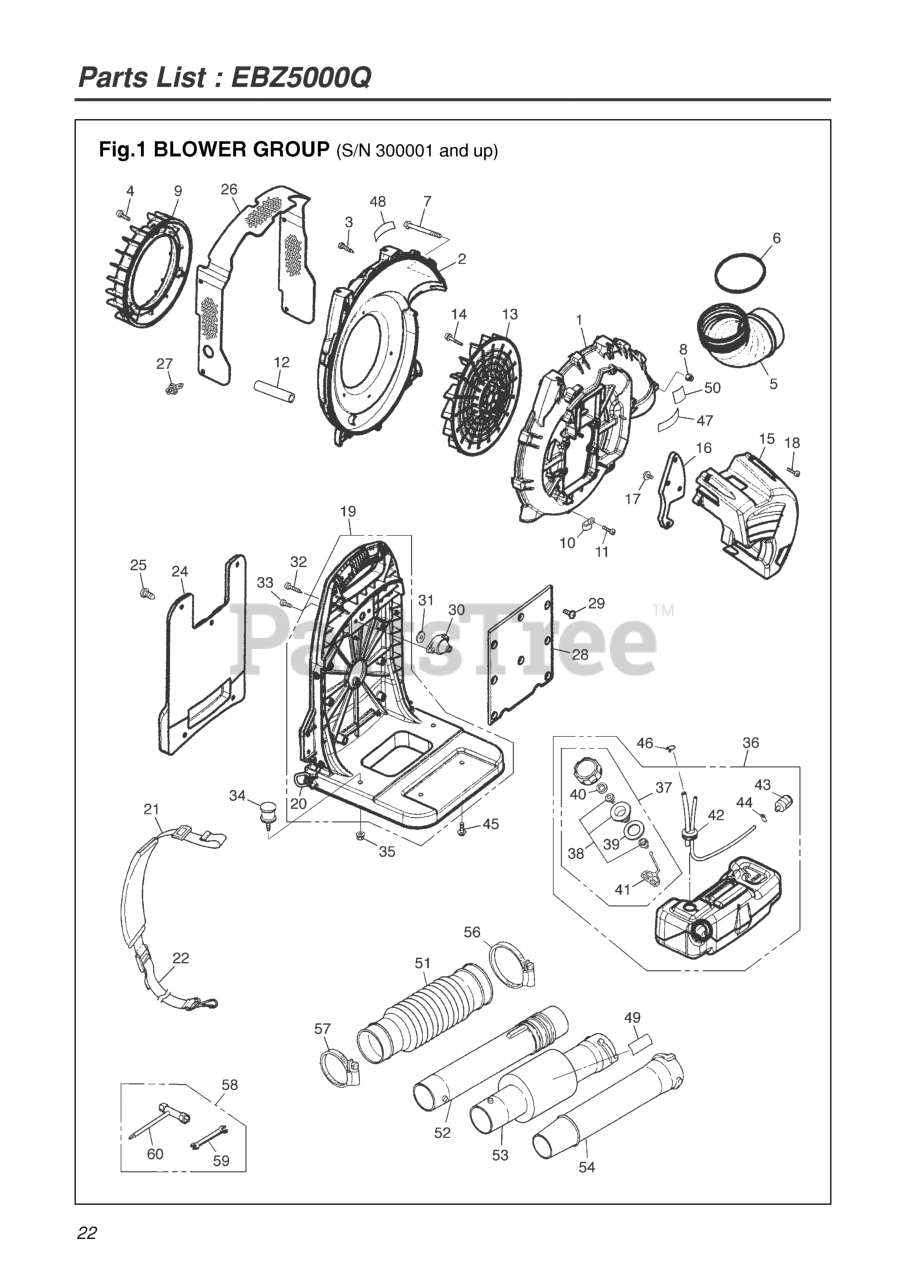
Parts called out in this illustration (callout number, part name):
1	CASE, VOLUTE
2	VOLUTE COVER(RPLS.T4017-31210)
3	SCREW
4	SCREW
5	ELBOW
6	O-RING
7	SCREW TORX
8	NUT (B)
10	CLAMP (RPLS 1140-72231)
12	TUBE (RPLS. 07270-01507)
13	FAN
14	BOLT
15	COVER, ENGINE
16	GLASS
17	SCREW
18	SCREW
19	FRAME COMPLETE
20	RING (REPLACES -21120)
21	USE T4017-32310
24	PAD
25	CLIP (RPLS 3490-21320)
26	NET COMPLETE
27	CLIP
29	SCREW
30	DAMPER, UPPER
31	WASHER
32	SCREW (RPLS T4970-54010)
33	SCREW TORX
34	DAMPER, LOWER
35	NUT, M6
36	TANK ASSEMBLY
37	CAP ASSY (RPLS -85201)
38	HOLDER (REPLACES -85230)
39	PACKING
40	FILTER
41	STOPPER
42	PIPE COMP.(RPLS 2756-85300)
43	FILTER ASSY
44	CLIP (REPLACES 2841-31280)
45	SCREW TORX
46	CLIP
47	LABEL, CAUTION (RPLS -31910)
48	LABEL, NET
49	LABEL,SILENCER
50	LABEL,65DB
51	HOSE
52	SWIVEL-JOINT (REPLACES -51200)
53	PIPE, SILENCER
54	PIPE, END
56	CLAMP
57	CLAMP (RPLS 3050-13230)
59	SPANNER, 8 X 10 (RPLS 2540- )
